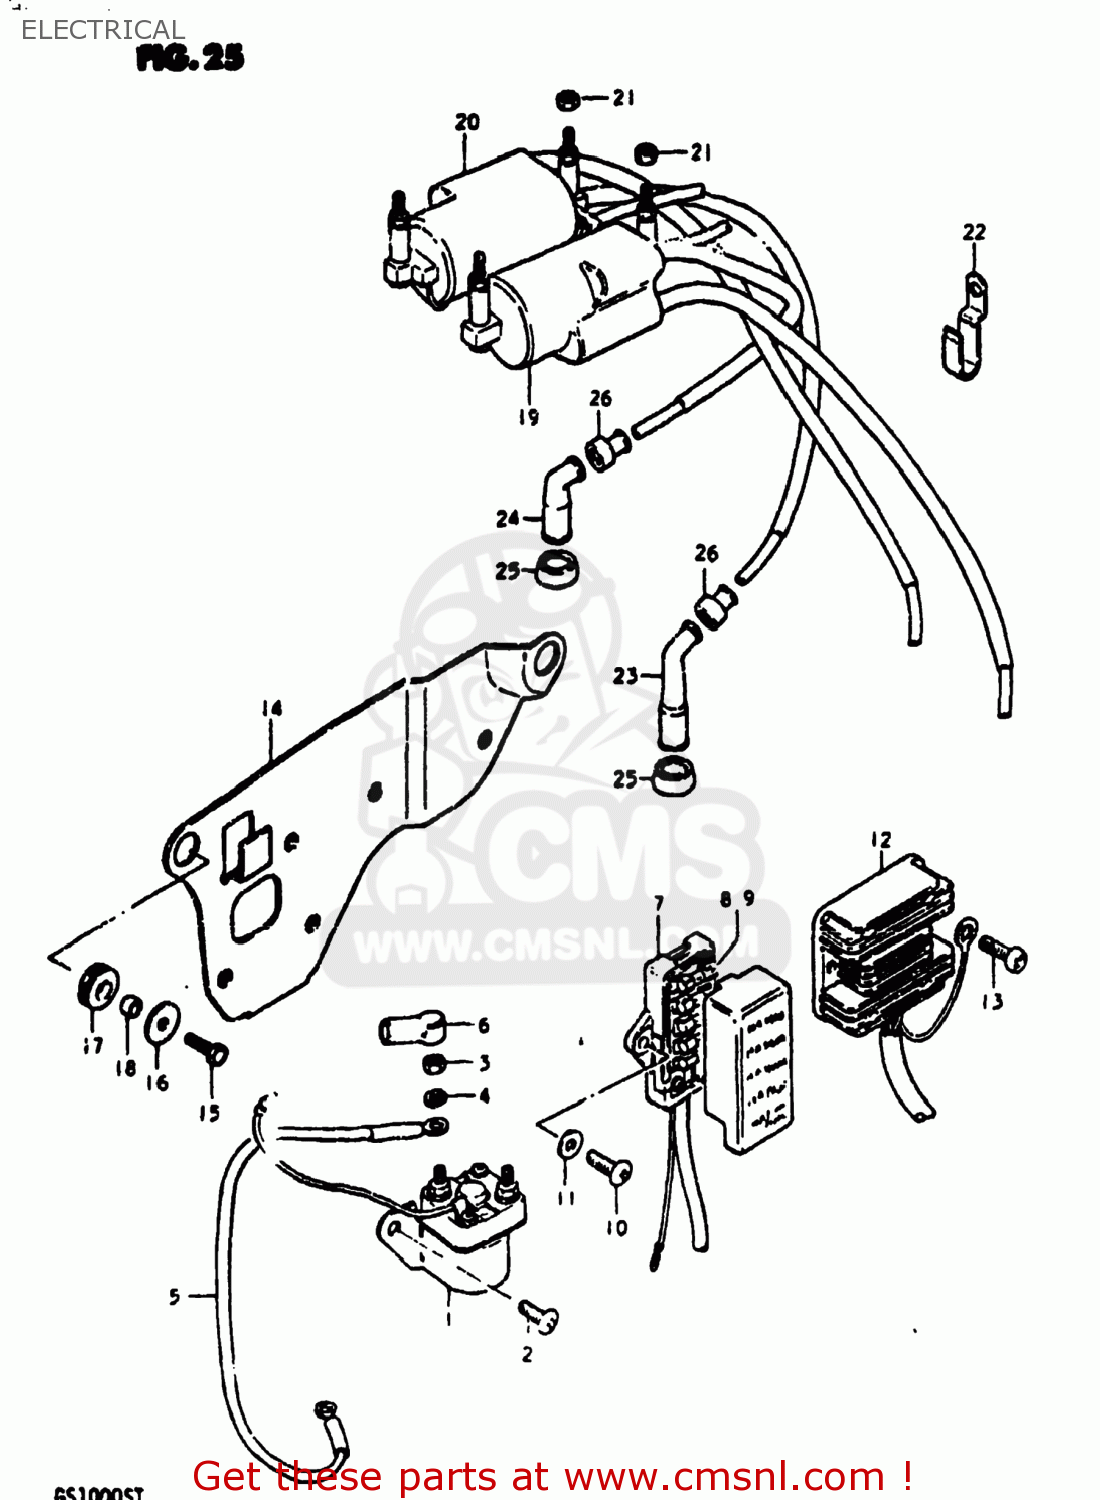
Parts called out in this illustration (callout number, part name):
1	RELAY ASSY,STARTING MOTOR
2	SCREW
3	NUT 6MM
4	LOCK WASHER
5	WIRE,STARTER MOTOR LEAD
6	CAP,STARTER RELAY
7	BOX ASSEMBLY,FUSE
8	FUSE(10A)
9	FUSE(15A)
10	SCREW
11	WASHER
12	RECTIFIER ASSEMBLY
13	SCREW 6X12
14	PLATE,ELECTRIC PARTS HOLDER
15	BOLT, UPPER
16	WASHER(6,5X22X1.6)
17	CUSHION
18	SPACER (7X9X7)
19	COIL ASSEMBLY,IGNITION
20	COIL ASSEMBLY,IGNITION
21	NUT
22	CLAMP
23	CAP ASSY,SPARK PLUG
24	CAP,SPARK PLUG
25	SEAL,SPARK PLUG
26	SEAL,SPARK PLU
